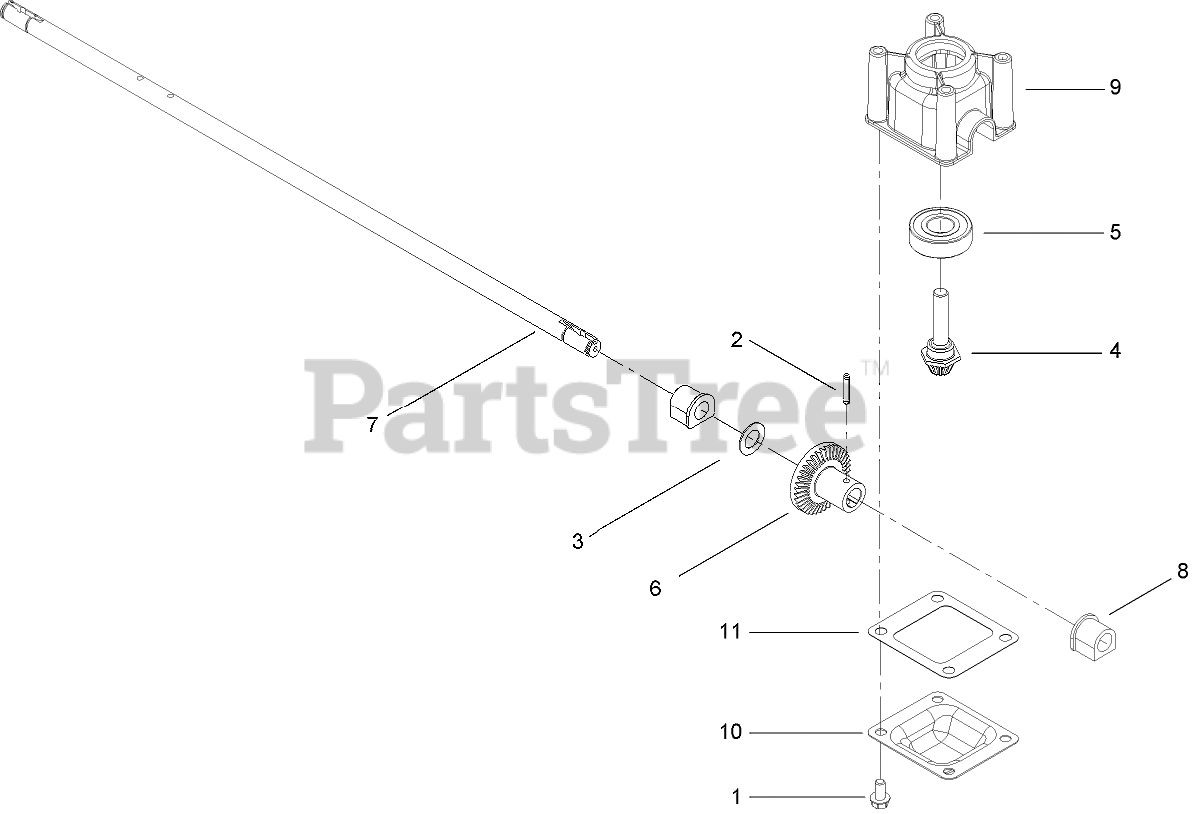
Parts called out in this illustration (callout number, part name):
1	SCREW-HWH
2	PIN-GROOVE
3	WASHER-PLAIN
4	PINION
5	BEARING-BALL
6	Gear-Bevel, 37t
7	Shaft-Output
8	Bushing-Shaft, Output
9	Gearcase-Upper
10	Cover-Gearcase
11	Gasket-Gearcase
